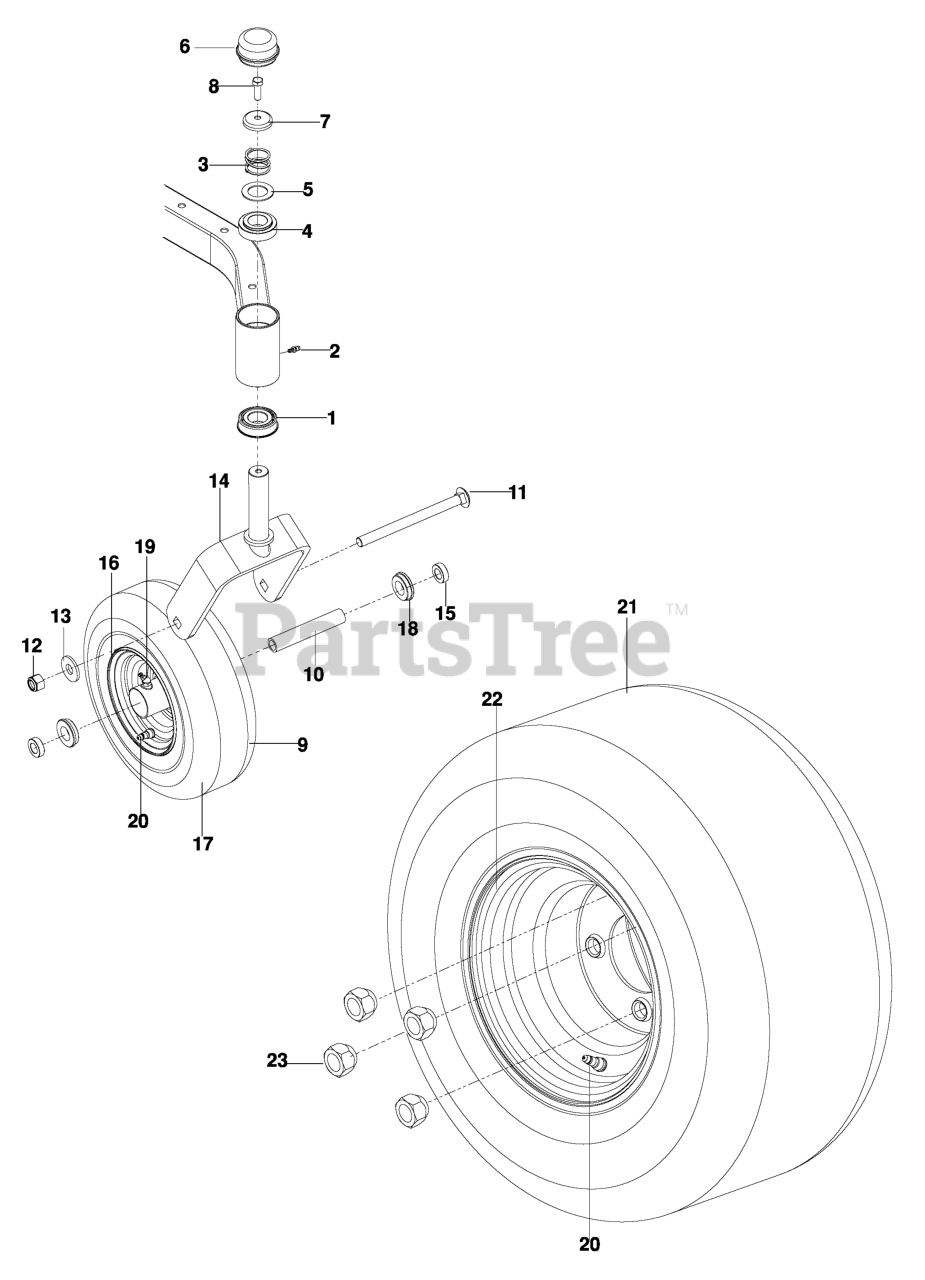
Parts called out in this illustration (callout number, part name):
1	BEARING FLANGED
2	ZERK, 3/16, DRIVE IN
3	SPRING, CASTER
4	BUSHING, CASTER
5	WASHER, 1.025 ID X 1.64
6	GREASE CAP
7	CASTER.PLUG
8	5/16-18X1 HHB G5W/NY
9	TIRE COMPLETE
11	RHSNB 1/2-13 X 6.50 GR2 ZD
12	NUT 1/2-13 HEX NYLOC ZD
13	WASH USS FLAT 1/2
14	YOKE.CASTER.ORANGE
15	SPACER, 5/16"
17	TIRE - CASTER
18	BEARING RETAINER
19	ZERK
20	VALVE STEM TR-412
21	TIRE ASM, 20 X 8-8
22	TIRE 20 X 8, TURF
23	RIM.8X7.W/8".OFFSET.SILVER.ZTR
24	LUG NUT 1/2F
